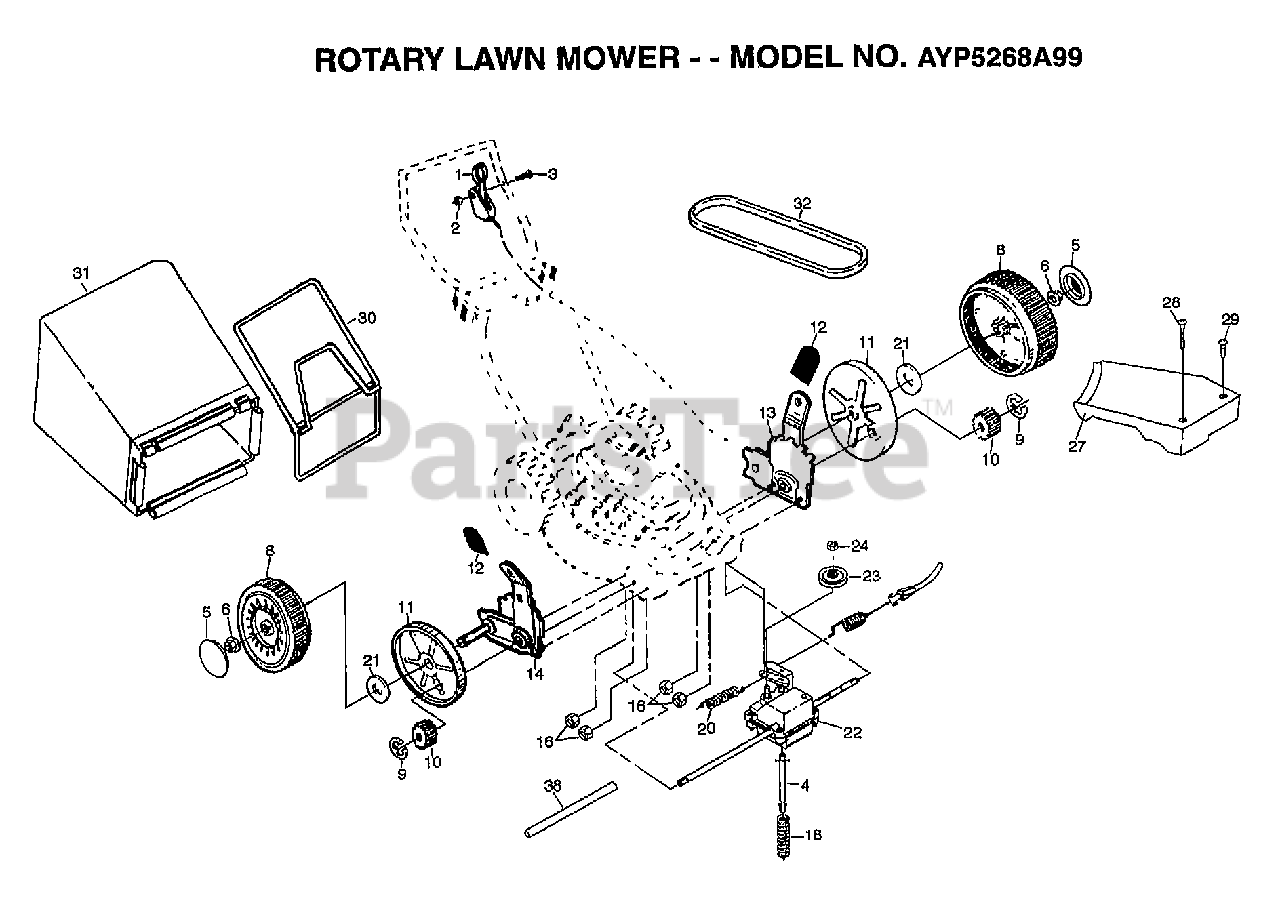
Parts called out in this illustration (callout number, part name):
1	CONTROL.DRV.56.25
2	LOCKNUT
3	PAN HEAD SCREW
4	SPRING.RETAINER.
5	HUB CAP
6	NUT.HXFLG.LOCK.
8	WHEEL.8X2.LP.PR
9	E-RING.7/16.RE.
10	PINION.GEAR
11	DUST SHROUD PM
12	KNOB PM
13	WHEEL.ADJ.ASM.LH.
14	WHEEL.ADJ.ASM.RH.
18	SPRING.TENSION
20	SPRING
21	WASHER FLUT
23	PULLEY.DRIVEN
24	LOCKNUT
27	"COVER.DRIVE 22""RD"
28	SCREWL.SLOT.TORXT
29	SCREW.SLOT.TORTX.
30	FRAME.CATCHER.2.5
31	GRASSBAG.250B1.BL
38	DRV SHAFT TUBE PM
